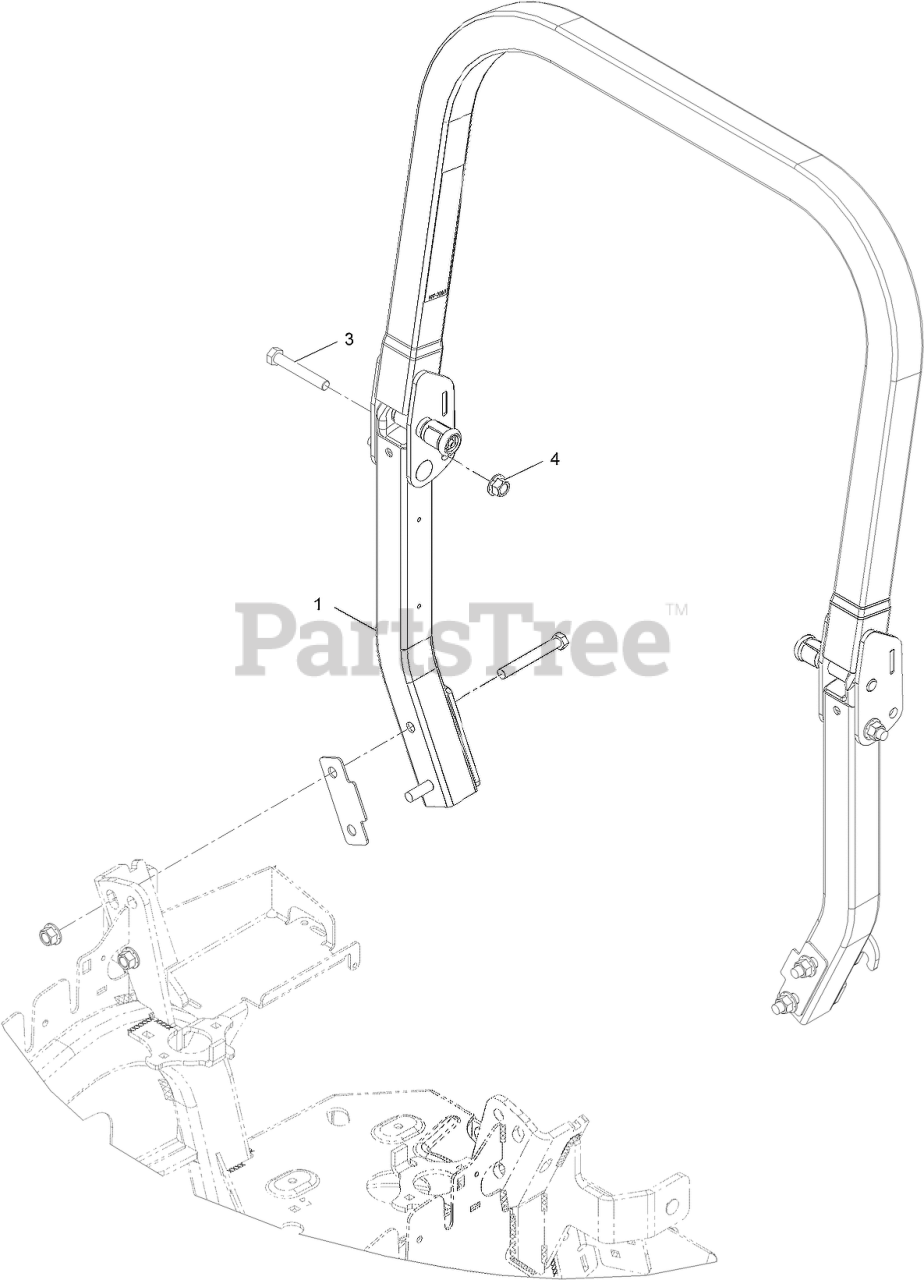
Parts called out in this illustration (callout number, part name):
1	ROPS ASM
3	SCREW-HH
4	Nut-Lock 1/2-13
